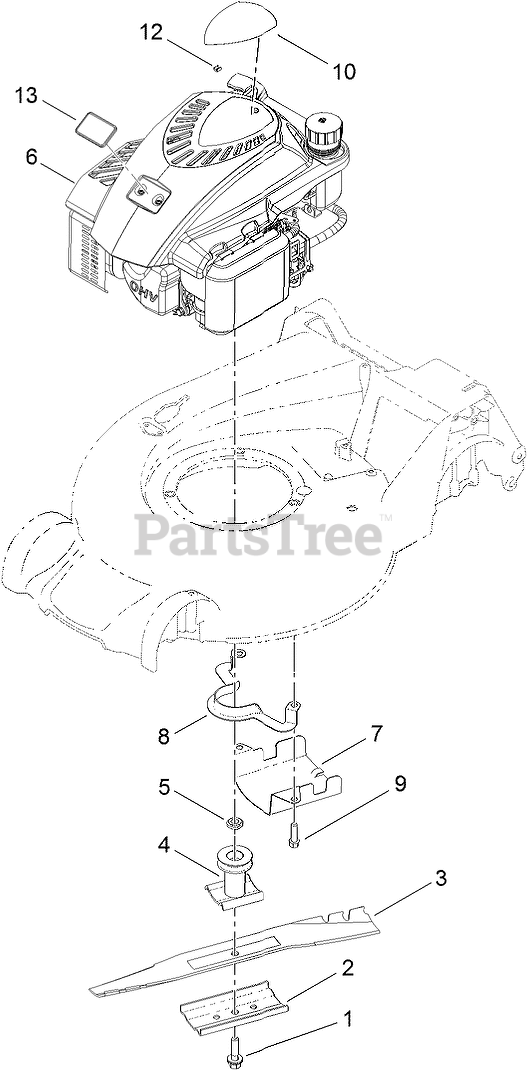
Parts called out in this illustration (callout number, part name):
1	BOLT-BLADE
2	SUPPORT-BLADE
4	DRIVER-BLADE
5	Spacer-Driver
6	ENGINE-1P65FC
7	SHIELD-GRASS
8	GUIDE-BELT
9	SCREW-MOUNT, ENGINE
10	DECAL-SHROUD
12	STOP-ROPE
13	PLATE-LOGO
